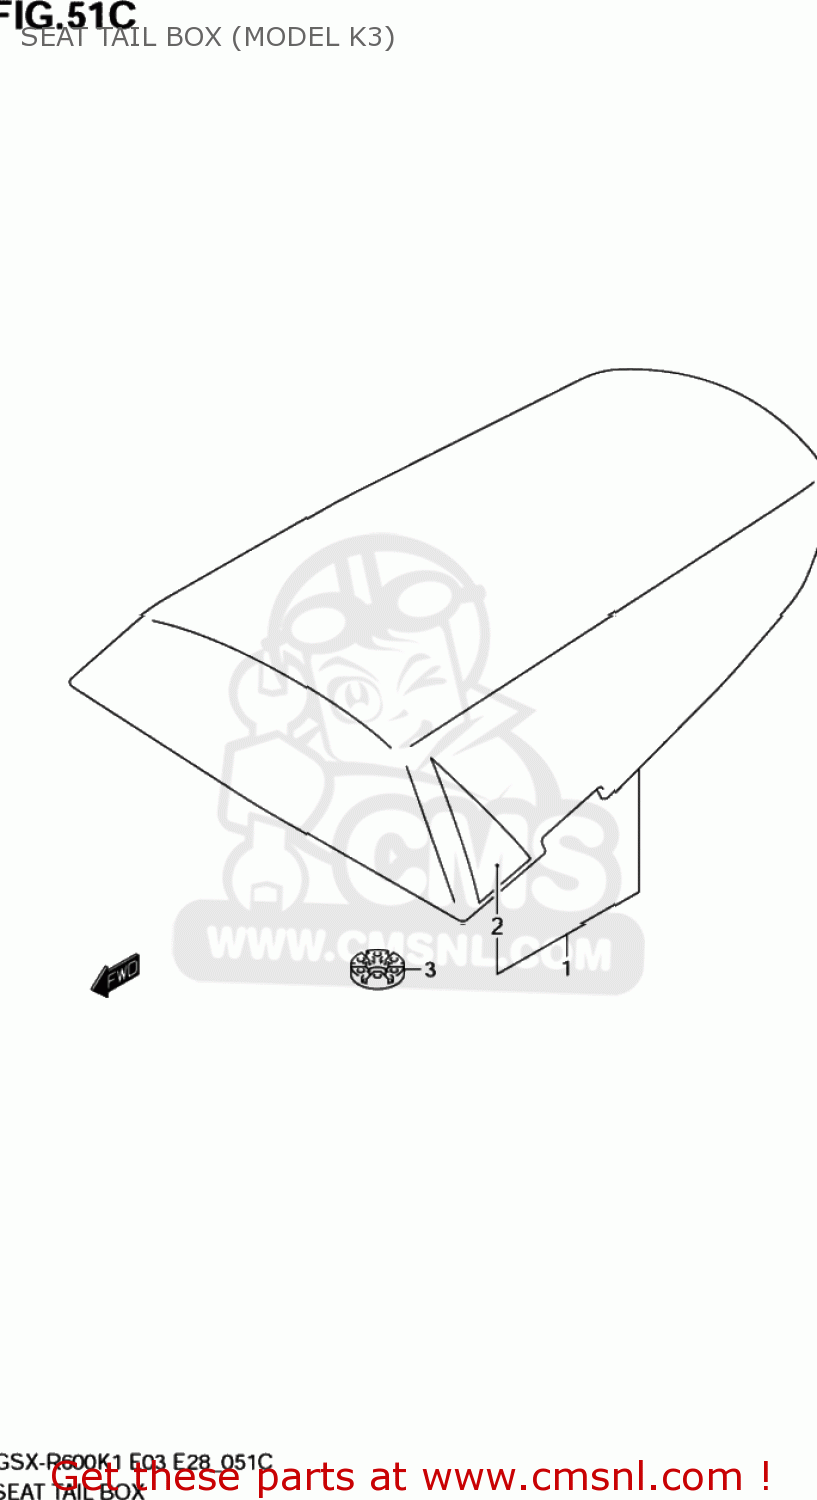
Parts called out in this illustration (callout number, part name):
1	BOX ASSY,SEAT TAIL(WHITE)
2	TAPE SET,BOX SEAT TAIL
3	CUSHION
